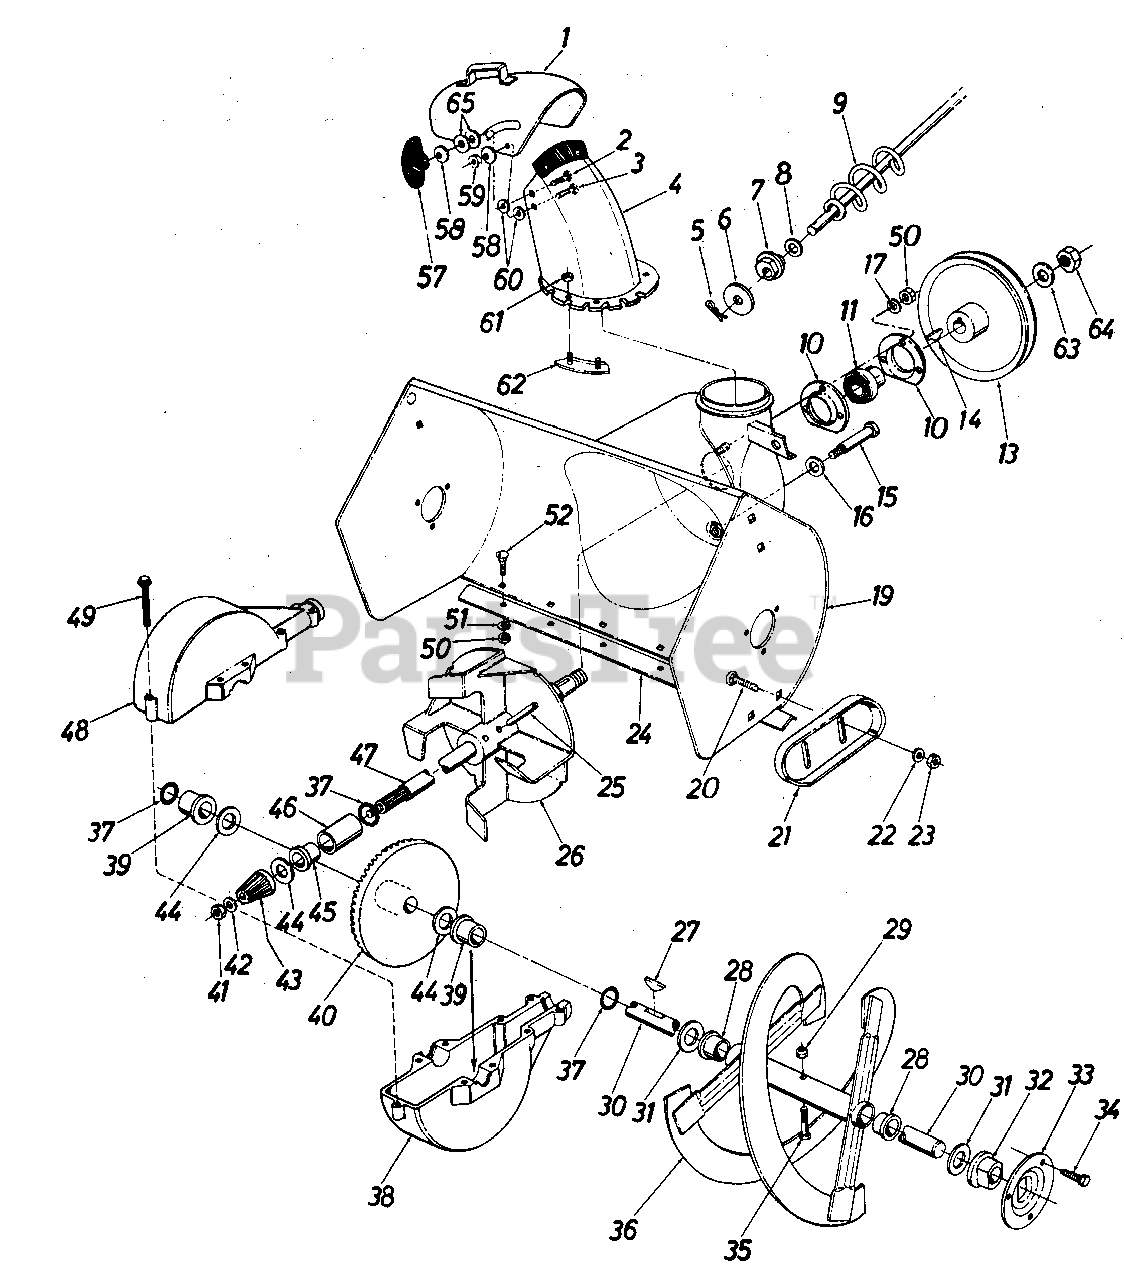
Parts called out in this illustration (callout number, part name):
1	Top Chute Ass'y.
2	Carriage Bolt 5/16-18 x 1.00" Lg.*
3	Carriage Bolt 5/16-18 x .62" Lg.*
4	Chute Ass'y.
5	Cotter Pin
6	Fl-Wash. .390 I.D. x 1.50" O.D.
7	Hex Bushing
8	Fl-Wash. .385 I.D. x .62" O.D.
9	Chute Crank Ass'y.
10	Bearing Housing
11	Self-Align Brg. w/Collar.75" I.D.
13	1/2" "V"-Pulley .625" I.D. x 7.50" O.D.
14	#61 Hi-Pro Key 3/16" x 5/8" Dia.
15	Shld. Bolt .50" Dia. x 2.11" Lg.
16	Bell-Wash. .40" I.D. x .88" O.D. x .06
17	L-Wash. 5/16" I.D.*
19	Blower Housing Ass'y.
20	Carriage Bolt 3/8-16 x .62" Lg. *
21	Slide Shoe
22	Bell-Wash. 3/8" I.D.
23	Hex Jam Nut 3/8-16 Thd.*
24	Shave Plate-24" Lg.
25	Spring Pin Spiral 1/4" Dia. x 1.50" Lg.
26	11" Dia. Blower Fan Ass'y.
27	#9 Hi-Pro Key 3/16 x 3/4" Dia.
28	Flange Brg. .75" I.D. x .88" O.D. x .62
29	Hex Ins. L-Nut 5/16-18
30	Spiral Axle
31	Fl-Wash. .75" I.D. x 1.50" O.D. x .06
32	Flange Brg. w/Flats .755"
33	Bearing Housing
34	Hex Wash. Hd. Self-Tap Scr. 5/16-24 X .50" Lg.
35	Hex Bolt 5/16-18 x 1.50" Lg.
36	Spiral Ass'y.-L.H.
37	"O"-Ring-3/4" I.D.
38	Bevel Gear Housing-Lower Half
39	Plastic Flange Brg. .755" I.D.
40	Bevel Gear
41	Hex Cent. L-Nut 5/16-24 Thd.
42	Fl-Wash. .34" I.D. x .62" O.D. x .06
43	Pinion Gear
44	Fl-Wash. .75" I.D. x 1.25" O.D. x .06
45	Flange Brg. .755" I.D.
46	Sleeve Brg. .755" I.D.
47	Blower Axle
48	Bevel Gear Housing- Upper Half
49	Hex Wash. Hd. Self-Tap Scr. 1/4-20 x 1.00" Lg.
50	Hex Nut 5/16-18 Thd.*
51	Bell-Wash. .34" I.D. x .88" O.D.
52	Carriage Bolt 5/16-18 x .62" Lg.*
57	Knob
58	Bell-Wash. .34" I.D. x .88" O.D.
59	Hex Cent. L-Nut 5/16-18 Thd.
60	Fl-Wash. .53n l.D. x 1.25" O.D. x .100
61	Hex Cent. L-Nut 1/4-20 Thd.
62	Chute Flange Keeper Ass'y.
63	Fl-Wash. .64" I.D. x .94" O.D. x .06
64	Hex Jam Nut 5/8-18 Thd.
65	Fl-Wash. .344 I.D. x 1.125 O.D.
